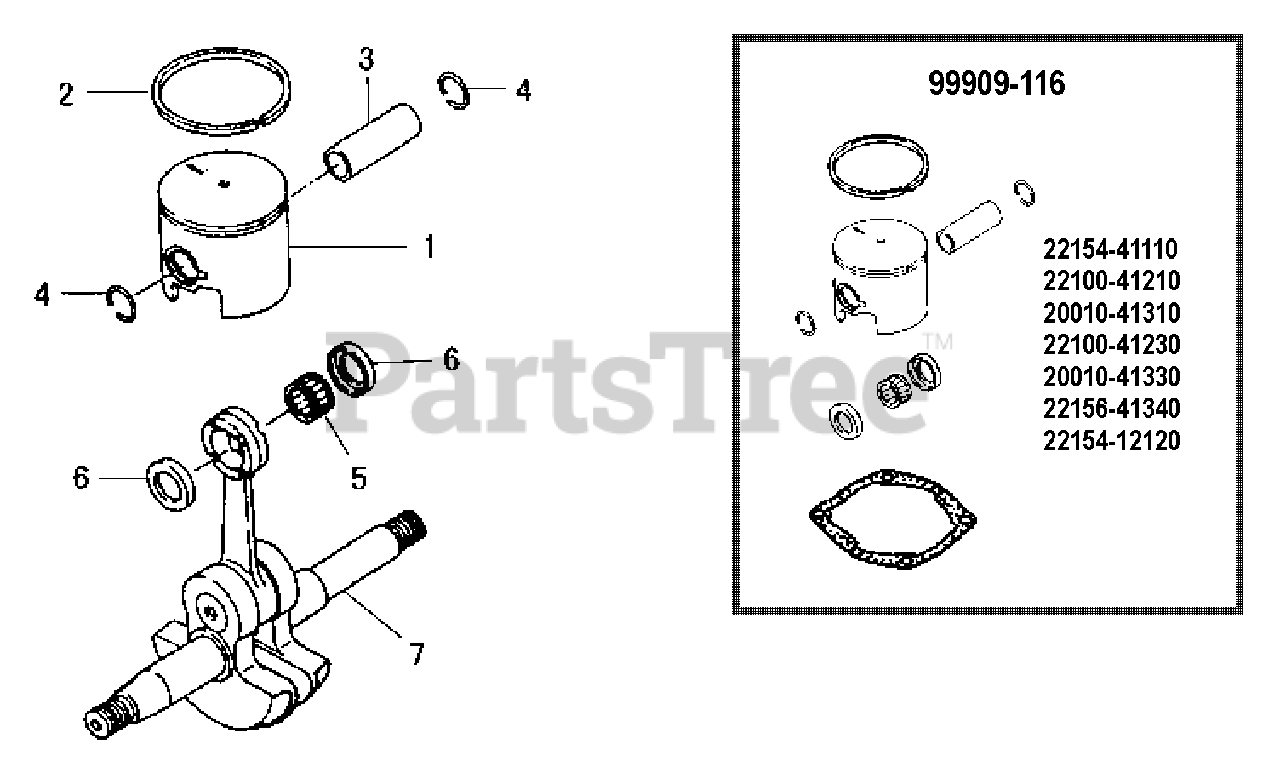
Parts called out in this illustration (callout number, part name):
1	PISTON
2	RING, PISTON
3	PIN, PISTON 10
4	RING, SNAP
5	BEARING, NEEDLE 10
6	WASHER, THRUST 10
7	CRANKSHAFT ASSY
99909-116	PISTON KIT
